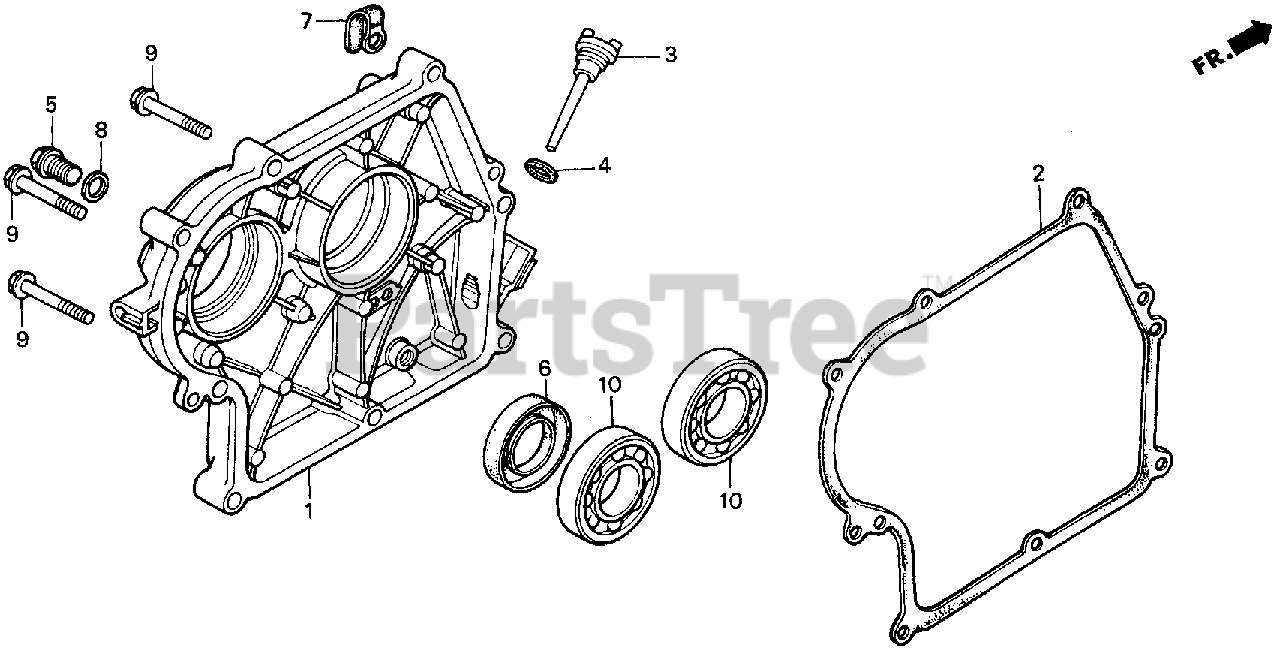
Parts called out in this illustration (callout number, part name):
1	COVER, CRANKCASE
2	GASKET, CASE COVER
3	CAP, OIL FILLER
4	GASKET, OIL FILLER CAP
5	BOLT, DRAIN PLUG
6	OIL SEAL (30X46X8)
8	WASHER, DRAIN PLUG (12MM)
9	BOLT, FLANGE (8X40)
10	BEARING, RADIAL BALL (6206)
